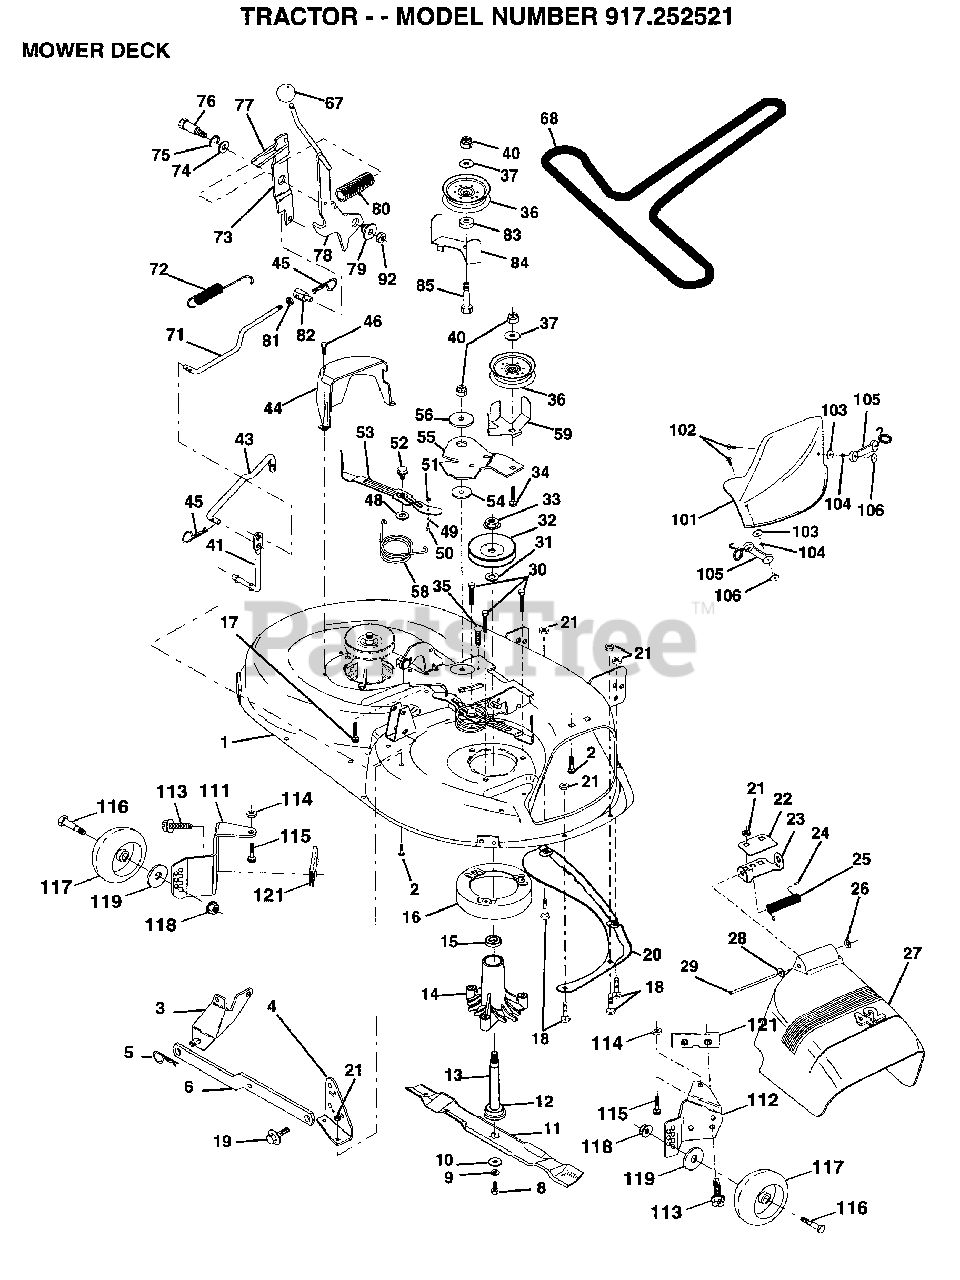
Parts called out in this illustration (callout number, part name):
1	DECK.WELD.42.
3	BRKT ASM SWAY BAR
4	BRKT DECK SW BAR
5	RETAINER RING
8	BLADE BOLT
10	WASHER.HARD.BLADE
11	"BLADE.42"" MULCHER"
12	BEARING.BALL
14	HSG ASM MANDREL
15	BEARING
16	STRIPPER RND MWR
17	BOLT RDHD 3/8-16
18	BOLT
19	BOLT SHD 5/16-18
22	STIFFENER BRKT
23	DEFLECTOR BRKT
24	CAP-SLEEVE LT
25	SPRING TORSION
26	NUT PUSH M
27	DEFLECTOR.SHIELD
28	WASHER
29	HINGE ROD
31	WASHER
35	XMAS TREE FASTNER
36	FLAT IDLER PULLEY
37	WASHER
41	PIVOT ROD
43	ROD CLUTCH W/NIBS
44	GUARD MAND LH BLK
46	SCREW.1/4-20X5/8
48	HARD SMALL WASHER
50	SHOULDER BOLT
52	BOLT.SHLD.5/16-18
53	BRAKE PAD ARM ASM
54	HARDENED WASHER
56	SPACER RETAINER
58	SPRING TORSN BRAK
59	GUARD IDLER TUV
67	KNOB T(3/8 HOLE)
68	BELT.V.T-PATH
71	ROD CLUTCH 38/42
72	RETURN SPRING
73	CLUTCH ARM SECOND
74	WASHER
75	RING
76	SHOULDER BOLT
77	SPRING KEEPER
79	BUSHING
81	NUT
82	TRUNION ADJ
83	WASHER
85	BOLT
101	"COVER.MULCH.42"""
102	SCREW
103	WASHER #10
106	WELDNUT
113	SCREW
116	BOLT.SHOULDER
117	WHEEL GAGE DONUT
118	LOCKNUT
119	WASHER
121	BRACKET.EXTRD.GWL
